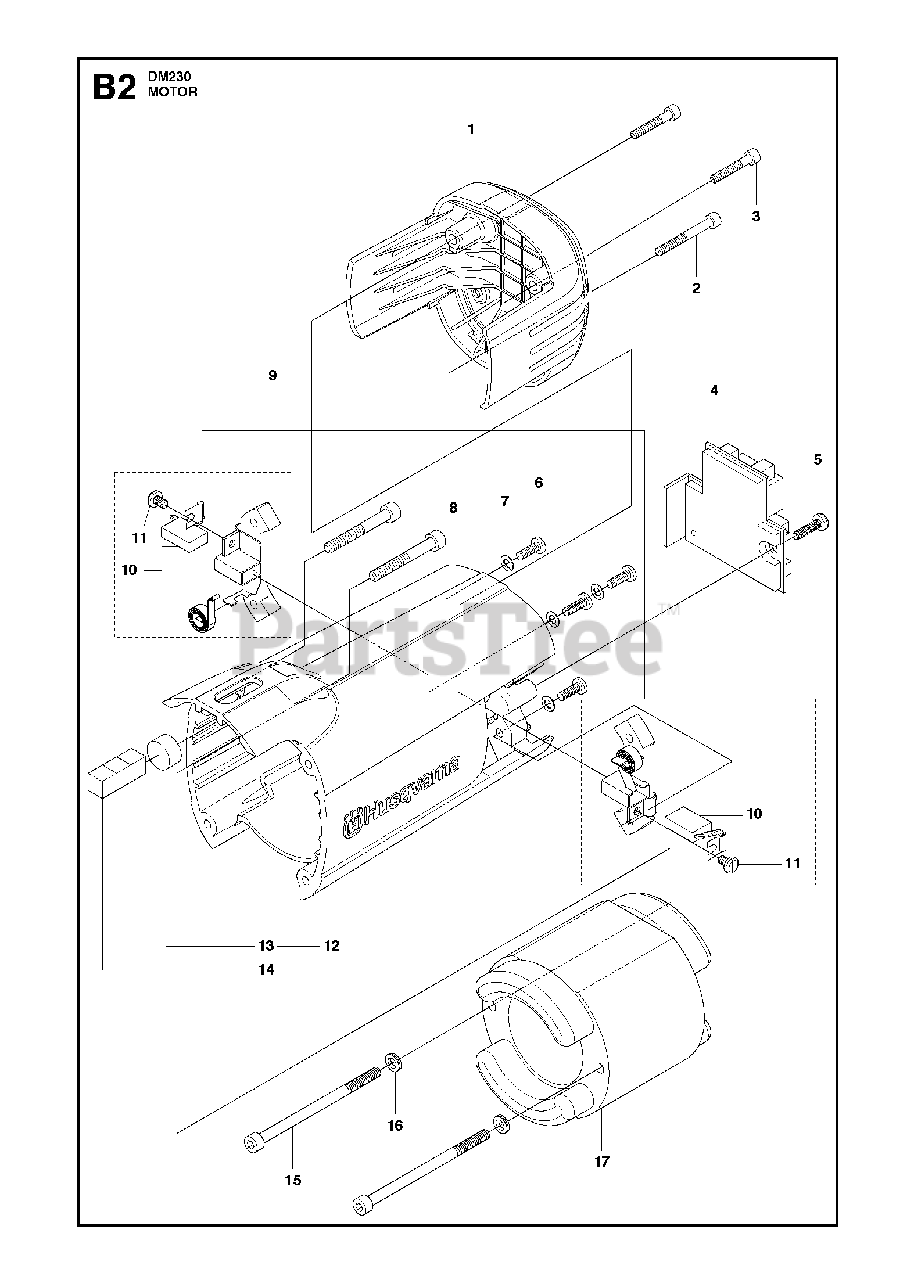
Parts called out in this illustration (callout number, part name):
2	SCREW IHSCFM
3	SCREW IHSCFM
4	PRINTED CIRCUIT ASSY120V
4	PRINTED CIRCUIT ASSY230V
7	SPRING WASHER
8	SCREW IHSCM
10	BRUSH KITContains two brushes and two springs
15	SCREW IHSCM
